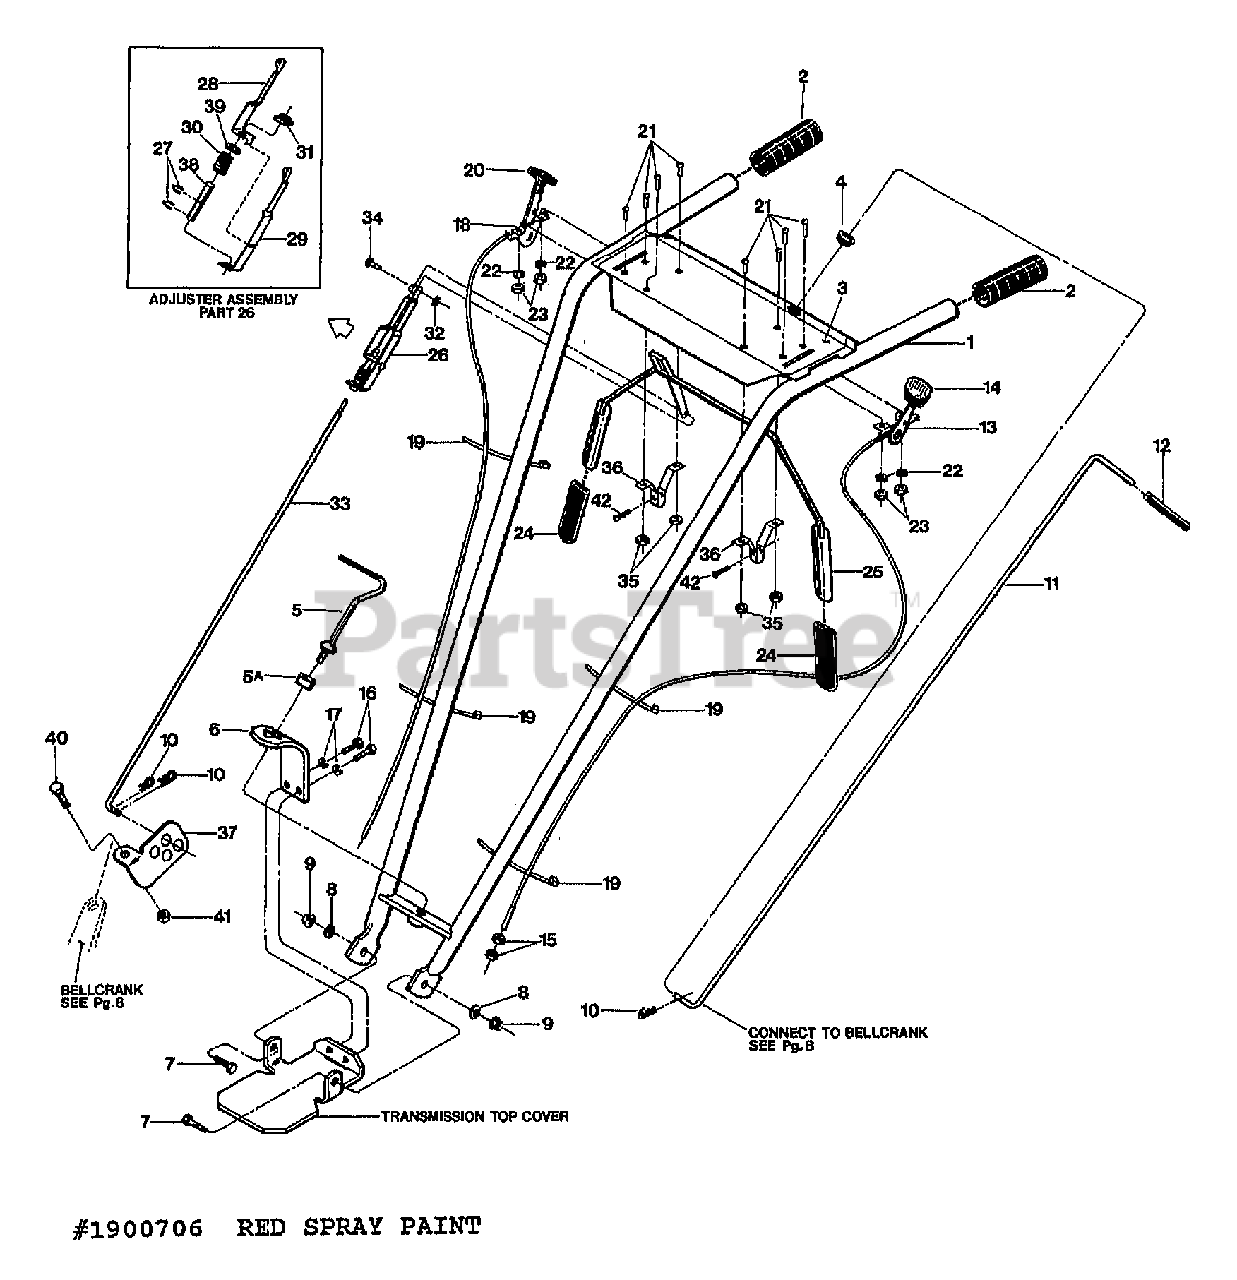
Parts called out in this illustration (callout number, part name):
1	ASSM-HANDLEBAR W/GRIPS (INCL. 2-5A)
2	GRIP-H/B 1" PONY/P-J OPC
3	DECAL-CONTROL PANEL
4	BUSHING-NYLON
5	ASSM-STUD H/B
5A	WASHER-1.0X.38X.375
6	PLATE-HANDLEBAR ADJUST
7	SCR-HH 3/8-16X1.0 G5 ZP
8	WASHER-FLAT 3/8 SAE (HANDLEBAR ATTACHMENT)
9	NUT-LOCK 3/8-16 NYLON ZP (HANDLEBAR ATTACHMENT)
10	PIN-CLIP .08
11	ROD-REV W/GRIP OPC (INCL. GRIP, #9198)
12	GRIP-CONTROL ROD
13	CABLE-WHEEL CLUTCH OPC (INCL. 14,15,19,21-23)
14	KNOB-WHEEL DRIVE CABLE
15	NUT-HEX 5/16-24
16	SCR-HH 3/8-16X.75 G5 ZP
17	WASHER-LK .375 @ DEPL
18	CABLE-THROTTLE PONY OPC
19	TIE-RED (PLASTIC)
20	KNOB-THROTTLE CABLE
21	SCR-RH M10-32X.5 MACH
22	WASHER-LK M10
23	NUT-HH M10-32X.125
24	GRIP-PADDLE SM FRAME OPC
25	BAIL W/GRIPS OPC (INCL. TWO GRIPS, INDEX #24)
26	ASSM-ADJUSTMENT OPC (INCL. 27-30,38-39)
27	RING-KLIP .500 ZINC
28	ADJUSTER-RT SIDE OPC
29	ADJUSTER-LT SIDE OPC
30	SPRING-ADJUSTER OPC
31	WELDNUT 5/16-18
32	RING-KLIP .188 DIA
33	ROD-CONTROL OPC
34	ASSM-PIN & CLIP (SMALL FRAME)
35	NUT W/LKWASHER #10-32 ZP
36	BRACKET-BAIL OPC
37	SWIVEL-SMALL FRAME
38	BUSHING-.5X.334X2.88
39	WASHER-.75X.51X.06 ZP
40	SCR-HH 1/4-20X.75 G5 ZP
41	NUT-LK 1/4-20
42	SCR-HWH 1/4-20 X .5 STH
